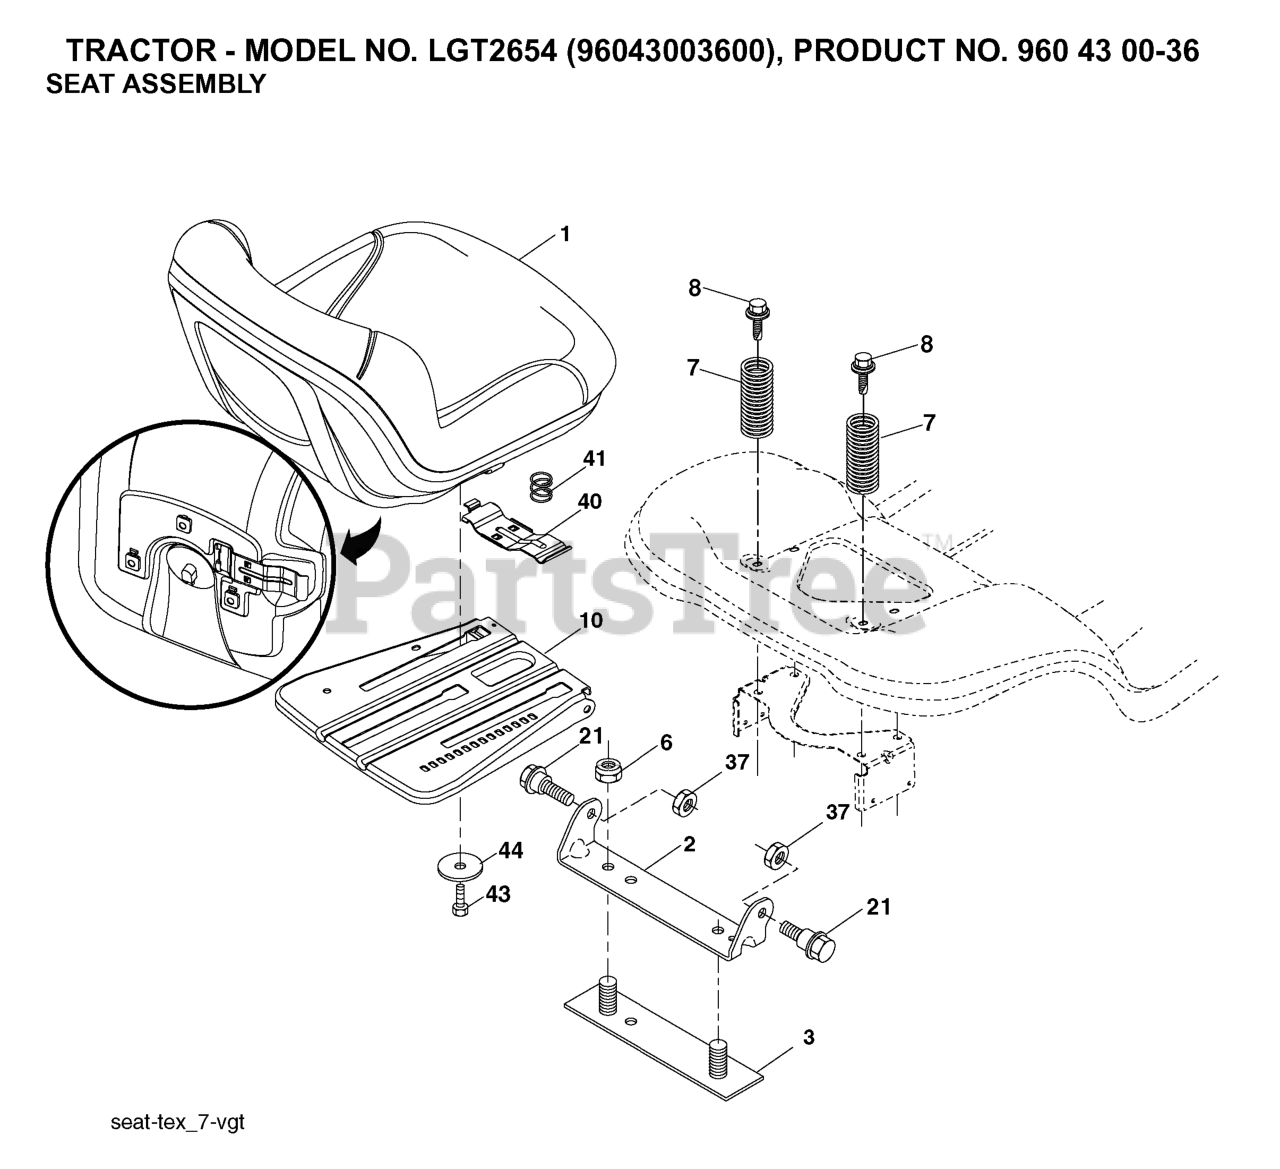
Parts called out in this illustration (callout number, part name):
1	SEAT - GREY
2	BRKT.PIVOT.FENDER
3	STRAP
6	NUT
7	SPRING COMPRESSION
8	BOLT.5/16-18UNCX3/4 W/SEMS.BLK
10	PAN.ASM.SEAT.3PT
21	BOLT.SHOULDER.5/16-18
37	NUT.71038.31-18.HEX.NYLOCK
40	HANDLE.SLIDE.SEAT.TEX.BLACK
41	SPRING.LATCH.SEAT.TEX
44	WASHER 13/32 X 2-3/8 X 12GA
